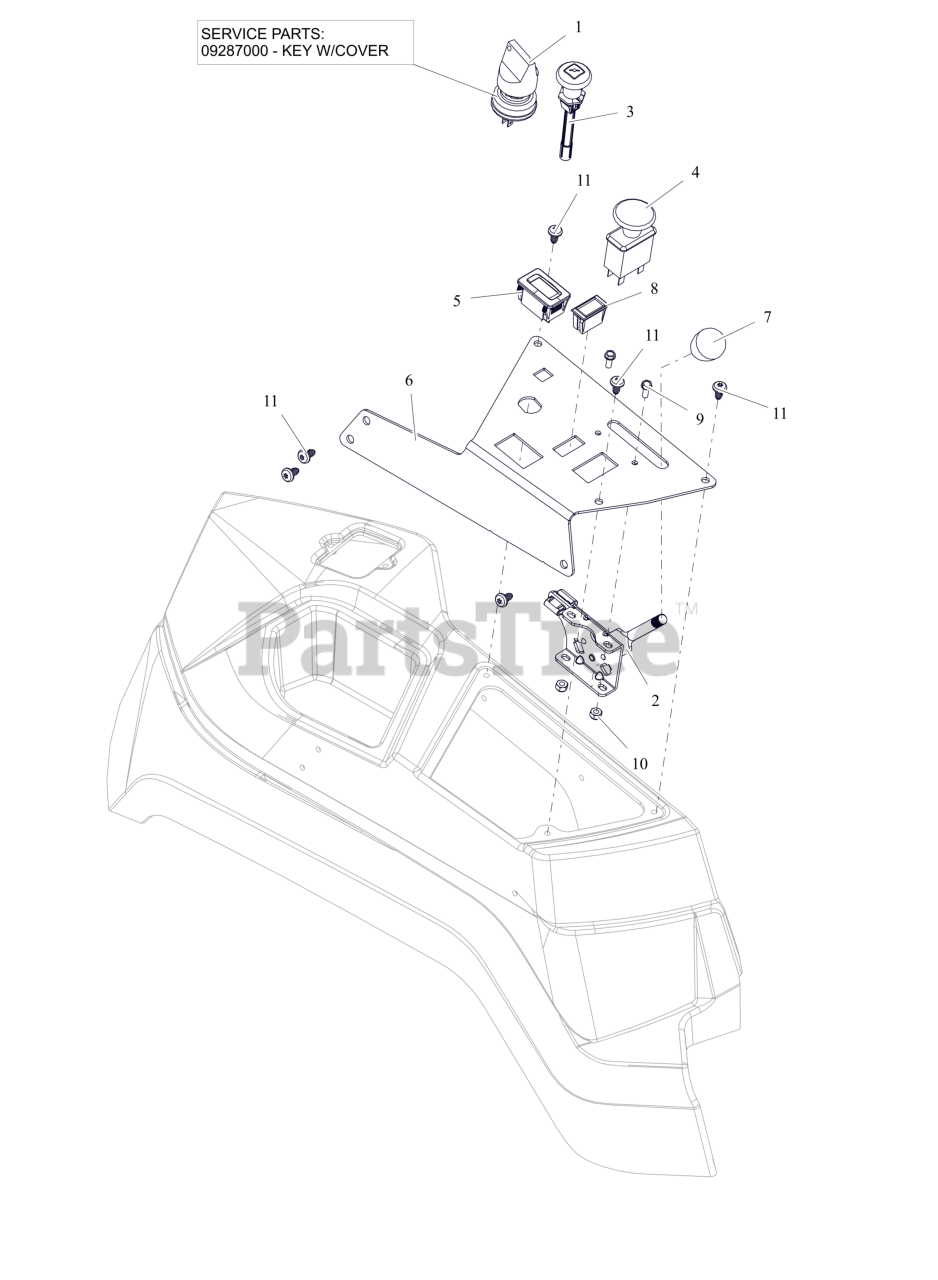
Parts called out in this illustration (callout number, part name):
1	SWITCH, IGNITION
1	KEY, W/ SHIELD
2	CABLE, PRO THROTTLE CONTROL
3	CABLE - CHOKE, SNAP-IN
4	SWITCH, CLUTCH
5	HOUR METER
6	PLATE, APEX CONTROL PANEL
7	KNOB-CONTROL-BLACK .38-16X.50
8	SWITCH,BLANK
9	BLT, HWH #10-24X.50 ZCC
10	NUT-LK-NYL #10-24 G2 ZCC
11	SCR-PAN .25-15X.50 6L H/LZB500
